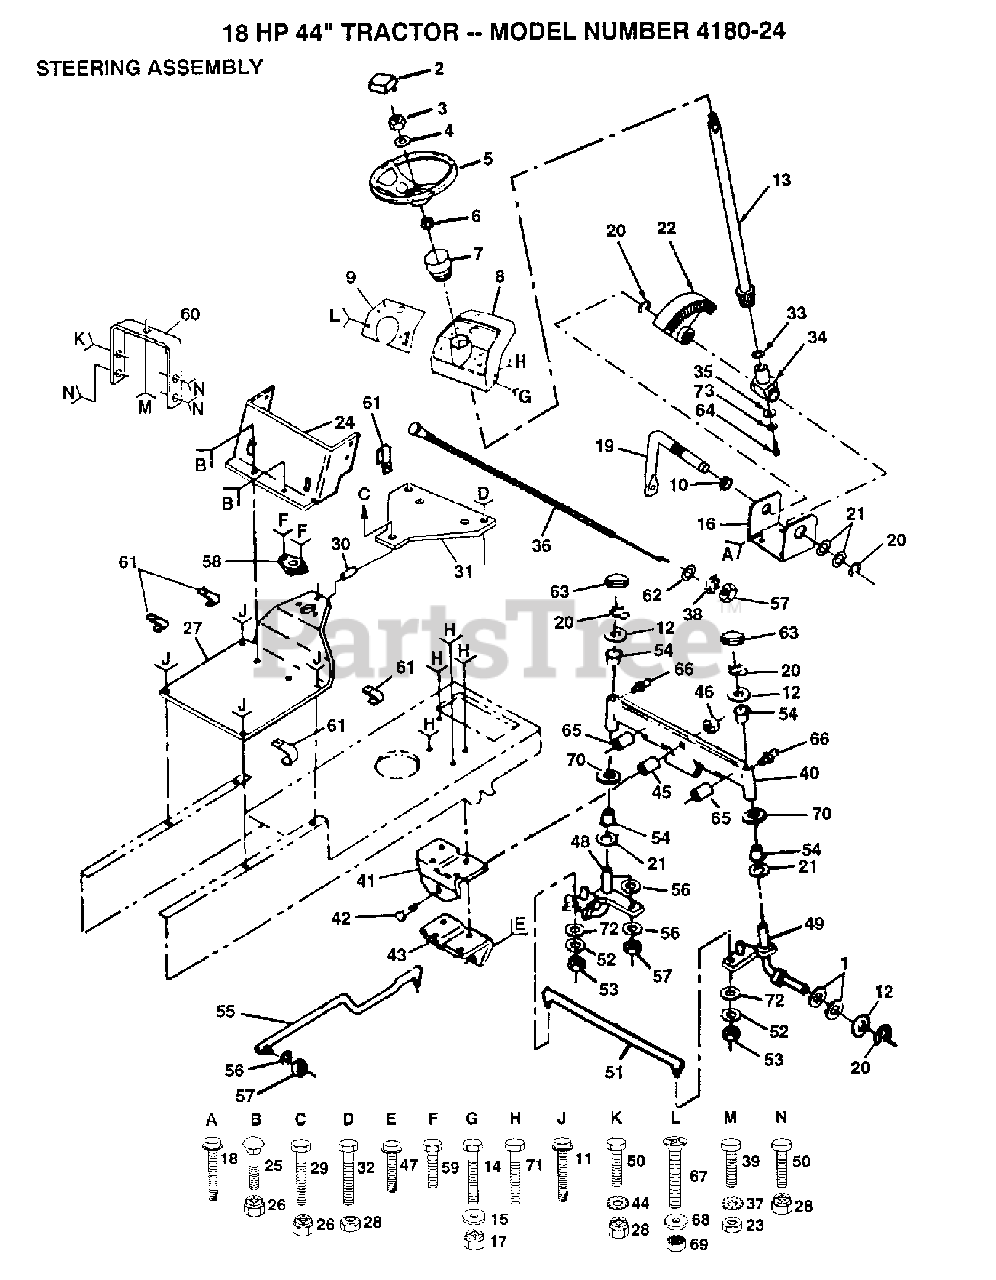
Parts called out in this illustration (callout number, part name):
2	INSERT STR WHL
3	NUT.HEX.1/2-20
5	Steering Wheel
10	NYLINER T (7283A)
11	SCREW LT
13	SHAFT ASS'Y STEER
14	BOLT
15	WASHER
16	BRKT,STEERING
17	LOCKNUT
19	SHAFT,PITMAN
20	RING CLIP
21	WASHER THRUST
22	GEAR,SECTOR
23	NUT
24	DASH LOWER YT NLA
26	LOCKNUT
28	LOCKNUT
31	PLATE SUPPORT T NLA
33	THRUST WASHER
34	SHAFT,SUPPORT
35	WASHER
36	CONTROL CHOKE
37	LOCKWASHER
38	LOCKWASHER
39	BOLT
40	AXLE ASSY T
41	SUPPORT-SADDLE LT NLA
43	SUP-SADDLE FRT LT
44	LOCKWASHER
46	LOCK NUT
47	SCREW LT
48	SPINDLE
52	LOCKWASHER
53	LOCKNUT
54	BEARING.STEERING.COLUMN
55	DRAG LINK
56	WASHER, LOCK 3/8
57	NUT
58	BUSHING
59	SCREW LT
60	SUPPORT ASS'Y
61	CLIP T
63	CAP.SPINDLE.BLACK
66	ZERK.GREASE.TAPERED
68	WASHER
71	SCREW SPECIAL
72	WASHER M
73	LOCKWASHER
